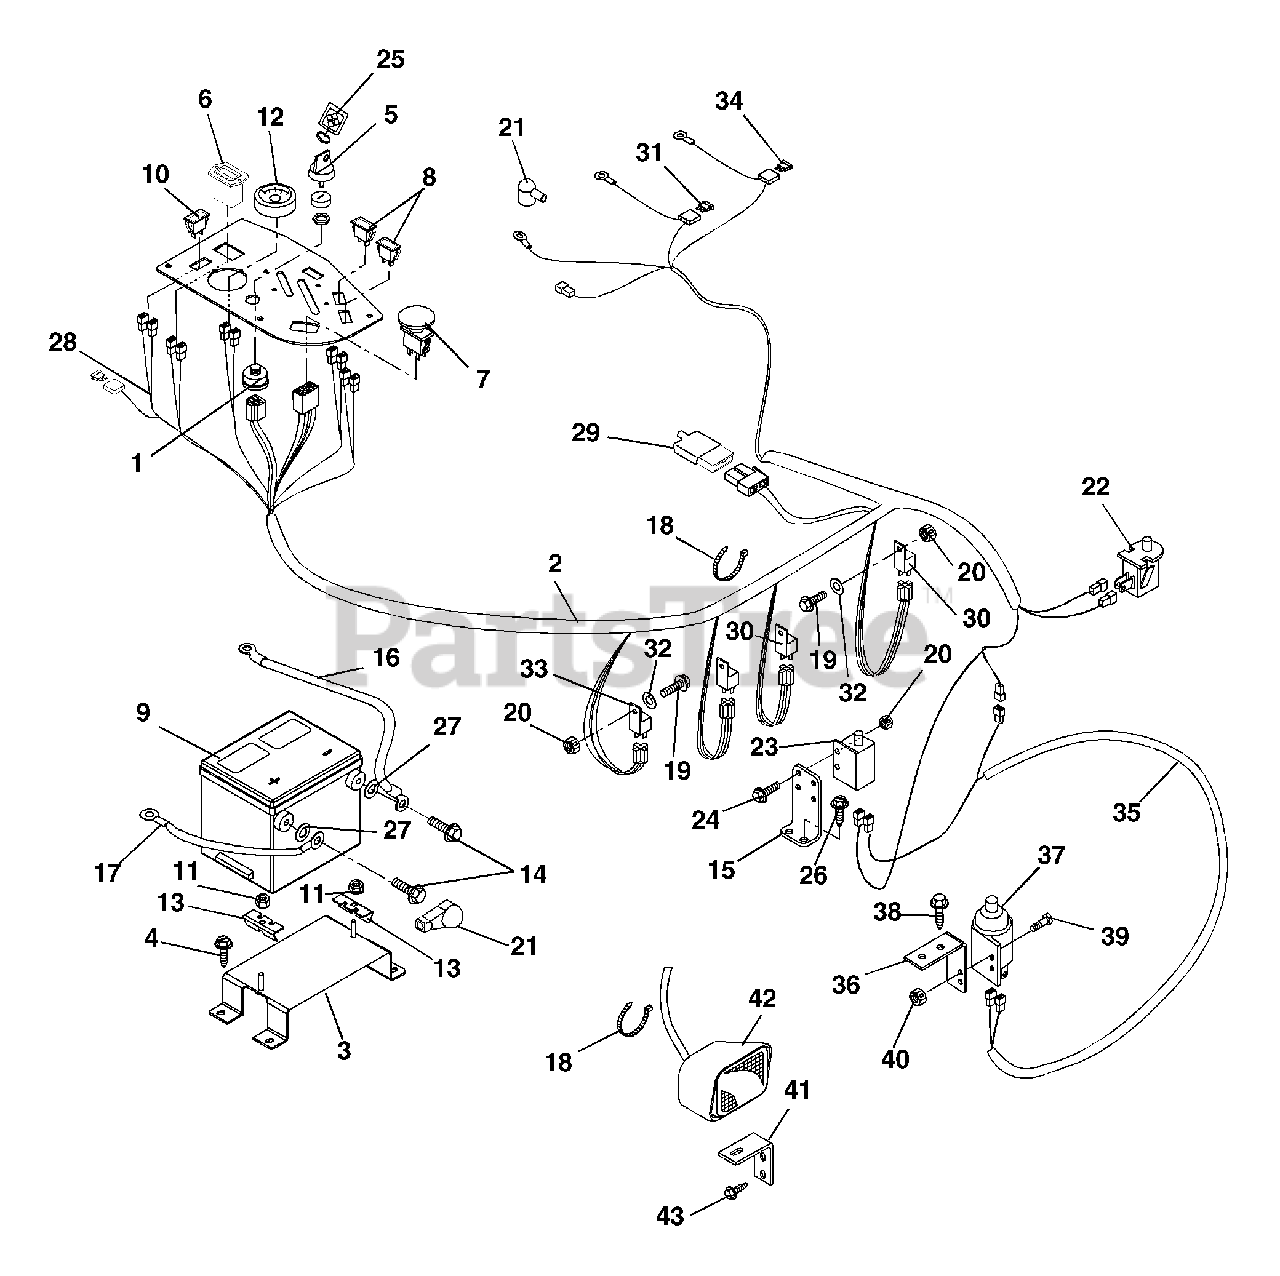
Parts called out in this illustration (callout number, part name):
1	Switch, Ignition (Diesel) (060, 061, 318, 319)
1	Switch, Ignition (058, 059)
2	Harness, Wiring (Diesel) (060, 061, 318, 319)
2	Harness, Wire (Gas) (058, 059)
3	Weldment, Battery Support
4	Screw-Tapping .38-16 x .75 Hex Washer Head
5	Key-with Cap
5	Ignition Key Set
6	Hour Meter
7	Switch-Clutch With Retainer Ring
8	Light-Indicator Kit (060, 061, 318, 319)
8	Light-Indicator Kit (058, 059)
9	Battery with Tube
10	Switch, Light
11	Nut-Locking-Top-Flange .31-18
12	Gauge, Temperature
13	Bracket, Battery Hold-Down
14	Bolt-Hex .25-20 x .75 Grade 5
15	Mount, Safety Switch
16	Positive Cable (060, 061, 318, 319)
16	Positive Cable (058, 059)
17	Cable, Negative Battery (060, 061, 318, 319)
17	Ground Cable (058, 059)
18	Cable Tie
19	Screw-Machine 10-24 x .75 Hex Washer Head (060, 061, 318, 319)
19	Screw-Machine 10-24 x .75 Hex Washer Head (058, 059)
20	Nut-Locking-Nylon 10-24 With Insert (060, 061, 318, 319)
20	Nut-Locking-Nylon 10-24 With Insert (058, 059)
21	Battery Terminal Boot, Red
22	Switch, Snap Mounting (N.O.)
23	Switch-Single Pole
24	Screw-Machine 10-24 x .75 Hex Washer Head
25	Key Chain
26	Screw-Tapping .25-20 x .50 Hex Washer Head
27	Washer-Flat-Steel .406 x 1.00 x .188
28	Fuse, 15 Amp
29	Diode, Connector Shell
30	Relay
31	Fuse, 30 Amp
32	Washer-Flat-Steel .25 x .562 x .049 (060, 061, 318, 319)
34	Fuse, 40 Amp
34	Fuse, 25 Amp
35	Harness, Wire Adapter CE (318, 319)
36	Mount- Switch (318, 319)
37	Switch-Single Pole (N.O.) with Cover (318, 319)
38	Screw-Tapping .31-18 x .50 Hex Washer Head (318, 319)
39	Screw-Machine 10-24 x .75 Hex Washer Head (318, 319)
40	Nut-Locking-Nylon 10-24 with Insert (318, 319)
41	Bracket, Headlight Mounting
42	Headlight
43	Screw-Tapping .38-16 x .50 Hex Washer Head
44	Boot, Eyelet Terminal
